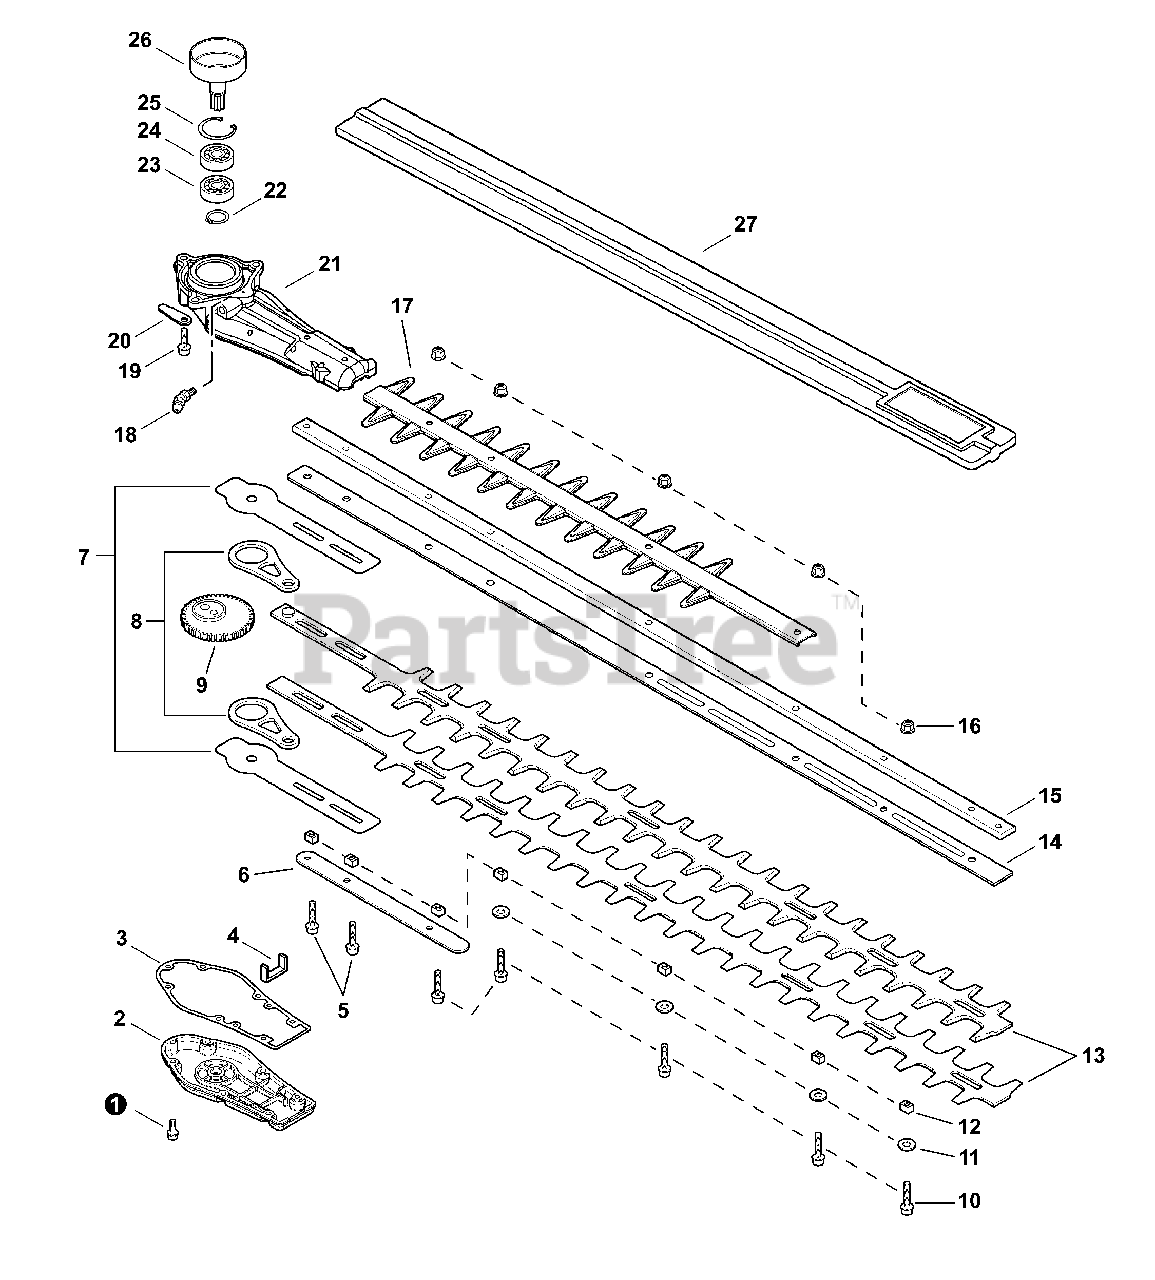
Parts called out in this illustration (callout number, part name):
1	SCREW - 4×16
2	LID, GEAR CASE
3	GASKET, GEAR CASE
5	SCREW - 5×25
6	SUPPORT, BLADE
7	PLATE, WEAR
8	ROD, CONNECTING
9	GEAR, SPUR
10	SCREW - 5×22
11	WASHER - 6
12	GUIDE, BLADE
13	BLADE, TRIMMER
14	SUPPORT, BLADE
15	SUPPORT, BLADE
16	LOCKNUT - 5
18	FITTING, GREASE
19	SCREW - 6×20
21	CASE, GEAR
22	RING, RETAINING - 14
23	BEARING, BALL - 6202
24	BEARING, BALL - 6202
25	RING, RETAINING - 35
26	DRUM, CLUTCH
27	COVER, BLADE - 24" (60cm)
